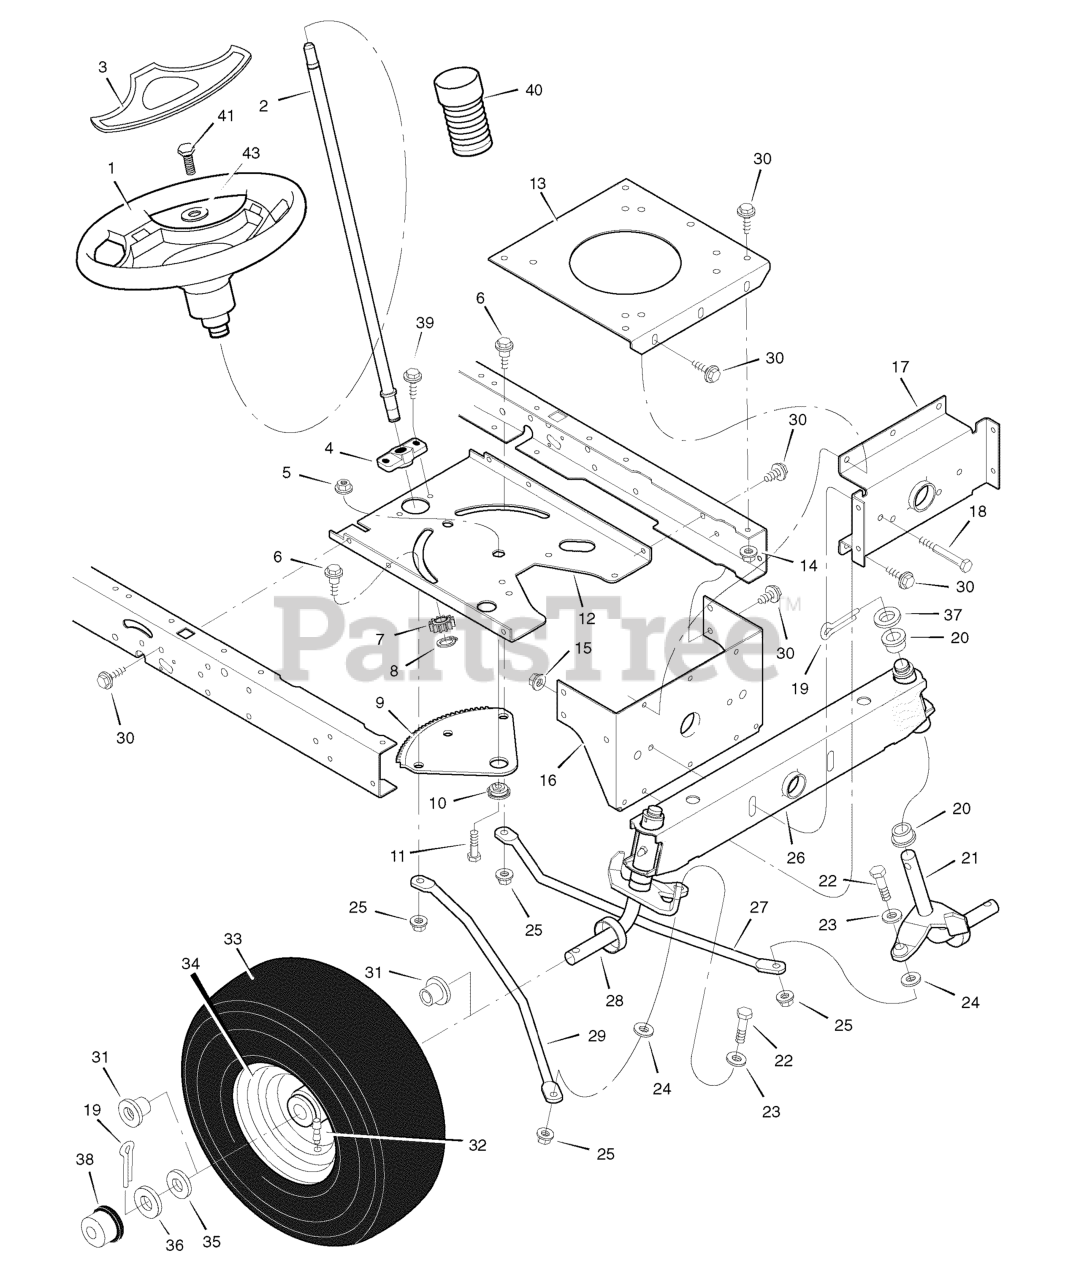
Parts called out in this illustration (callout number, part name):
1	Wheel, Steering
2	Post, Steering
3	Cover, Steering Wheel
4	Bearing
5	Nut, Flange
6	Bolt, Shoulder
7	Gear, Pinion
8	Ring, Snap
9	Gear, Sector
10	Bearing
11	CAPSCREW, Hex Head, 5/16-18 x 1
12	Plate, Steering
13	Plate, Engine
14	Nut, Flange
15	Nut, Flange
16	Bracket, Hanger
17	Axle, Hanger
19	Pin, Cotter
20	Bearing
21	Spindle Assembly, Left
22	Bolt
23	Washer
24	Washer
25	Nut, Flange
26	Axle Assembly
27	Drag Link, Left
28	Spindle Assembly, Right
29	Drag Link, Right
31	Bearing Wheel
32	Stem, Valve
34	Wheel and Tire Assembly
38	Hub Cap
40	Bellows
41	Screw, Hex
43	Washer
